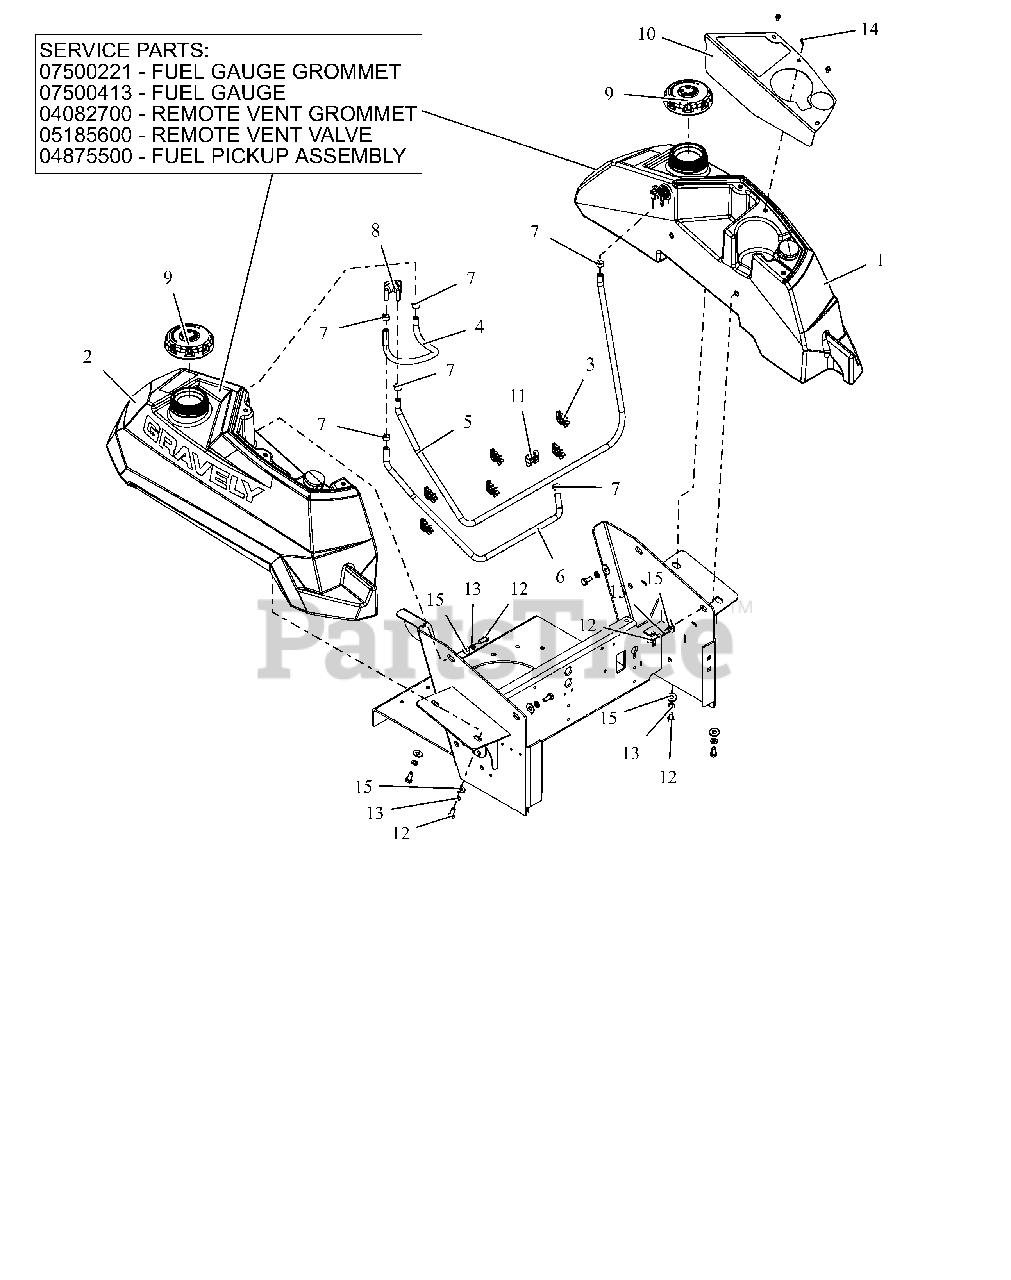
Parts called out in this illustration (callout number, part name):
1	ASM, LH PT100 CARB FUEL TANK
2	ASM, RH PT100 CARB FUEL TANK
2	GROMMET, FUEL GAUGE
2	GAUGE, REMOTE SEALED FUEL
2	GROMMET, REMOTE VENT NITRILE
2	VALVE, COMBINATION VENT 3/16
2	ASSM,LRG TANK FUEL PICKUP LINE
3	WIRE CLIP
4	HOSE, .25 LOW-PERM BULK GAS
5	HOSE, .25 LOW-PERM BULK GAS
6	HOSE, .25 LOW-PERM BULK GAS
7	CLAMP, FUEL LINE
8	VALVE, FUEL
9	CAP, FUEL NONVENT AUTOLOCK
10	PT100 CUPHOLDER PANEL - RED
11	CLIP, T, .38-.50
12	@BLT-HEX .31-18X.75 GR5 YWZC
13	@WSHR-LK .31X.078 REG YWZC
14	SCR-MCH 10-24X.38 HWHSTAINLESS
15	@WSHR-FL-STL.38X.875X.083 YWZC
